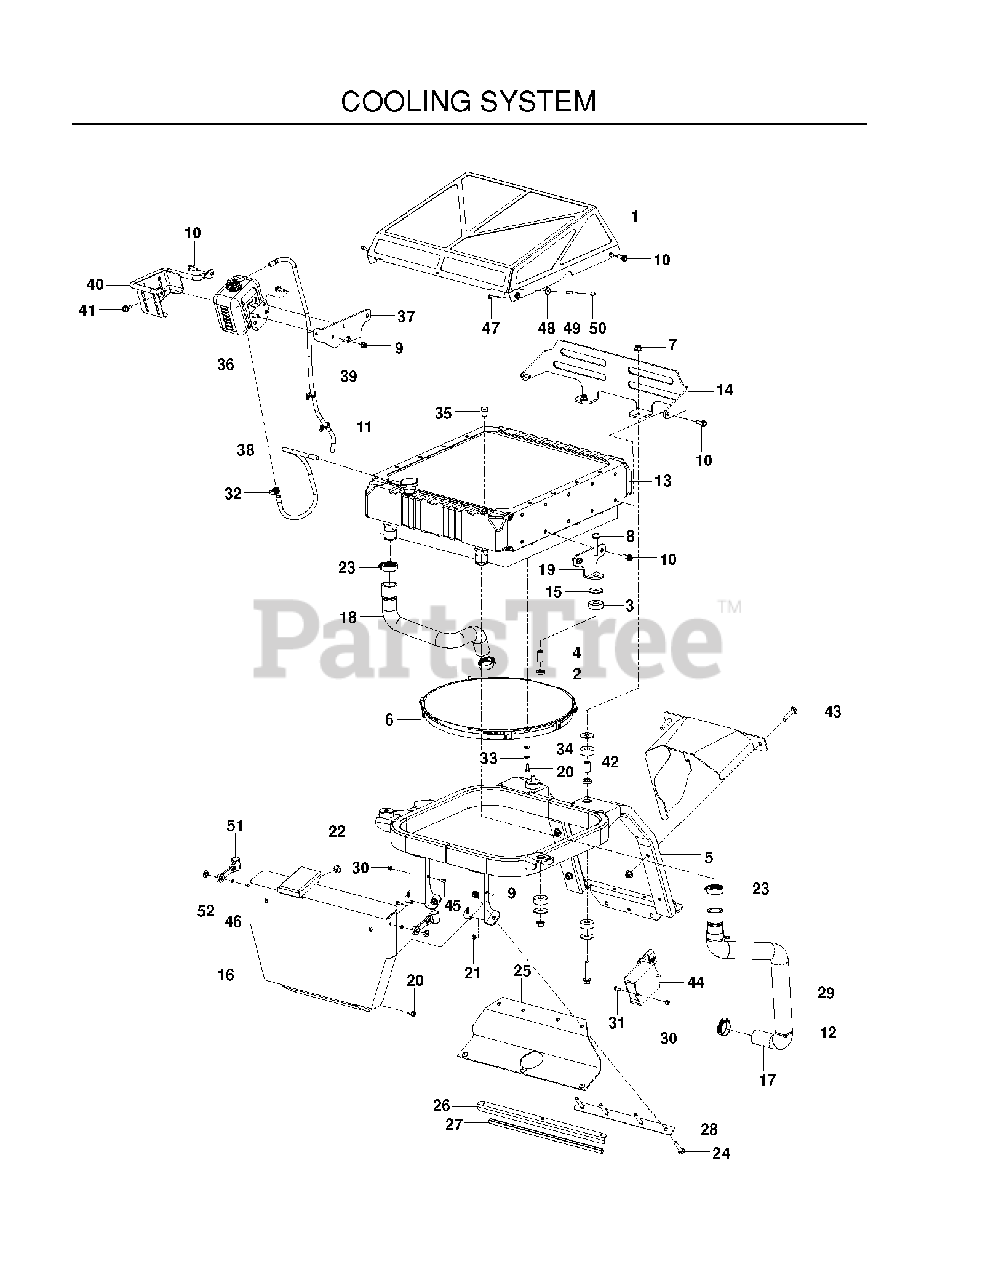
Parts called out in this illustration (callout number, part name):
2	ISO-MOUNT INSERT
3	ISO-MOUNT BUSHING
4	ISO MT. BUSHING
5	MOUNT, RADIATOR, BLUE
6	FAN, ELECTRIC
7	NUT 3/8-16 HEX FLG NYLOC ZD
8	HHFS 3/8-16 X 2.0 GD 5
9	5/16-18 NYLOC FLANGE NUT
10	HHFS 5/16-18 X 3/4
11	TIE WRAP, 8-3/8", W/CLIP
12	TIE, PLASTIC
13	RADIATOR
16	GUARD, HOSE W/DECALS
20	SCREW- 1/4-20 X 5/8
21	JAM NUT 1/4C
22	GROMMET, BUMPER
24	RHSNB 5/16-18X1 3/4
25	GUARD, BELT
27	FLEX TRIM, BLACK
28	STRAP, GUARD
29	SLEEVE, HOSE
30	NUT 10-24 NYLOC
31	SCREW #10-24 X 5/8
32	CLAMP, WORM GEAR, NO. 4
33	LOCKWASHER 1/4"
34	WASHER 1/4 SAE
36	BOTTLE, OVERFLOW
40	GUARD, OVERFLOW, BLK
41	BOLT 5/16-18 X 3/4
42	SHIELD, BELT W/DECAL - BL
43	RHSNB 3/8-16X1-3/4
45	HCS #10-24 X 1/2
46	WASHER - 3/8
47	SCREW #10-24 X 1-1/8 ZD SPEC
49	SPACER LT
